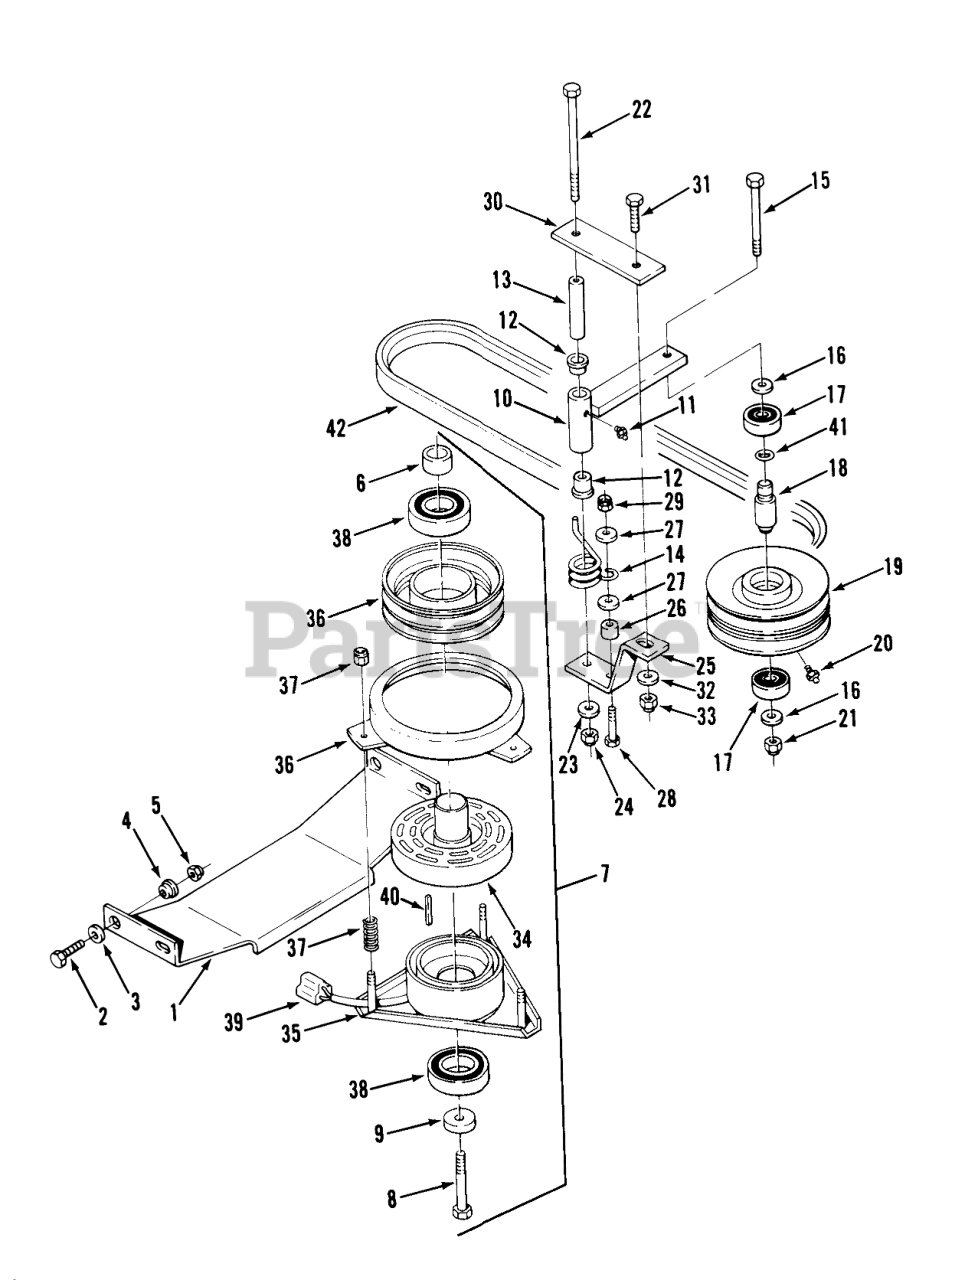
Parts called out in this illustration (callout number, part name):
1	BRACKET CLUTCH ST R
2	HHCS
3	WASHER 5/16 SAE
4	BUSHING
5	Nut
6	SPACER
7	CLUTCH
8	Bolt 7/16-20 x 2 3/4
9	WASHER
10	Arm-Idler
11	Fitting-Grease
12	BUSHING
13	SPACER
14	SPRING-TORSION
15	HHCS
16	Washer
17	BEARING-BALL
18	SPACER-PTO IDLER
19	PULLEY 2- GROOVE
20	Zerk
21	NUT
22	Bolt 3/8-16 x 4
23	Washer
24	NUT
25	Bracket-Idler
26	Spacer
27	Collar
28	Bolt
29	Nut
30	Plate
31	Bolt
32	Washer
33	NUT
34	ROTOR ASSEMBLY
35	Field (Includes Bearing) 616-Z, 620-Z
36	Armature and Pulley (Includes Bearing)
37	ACCESS SPRING & NUT
38	BEARING-ELEC CLUTCH
39	CONNECTOR BODY B
41	O RING
42	V-BELT
